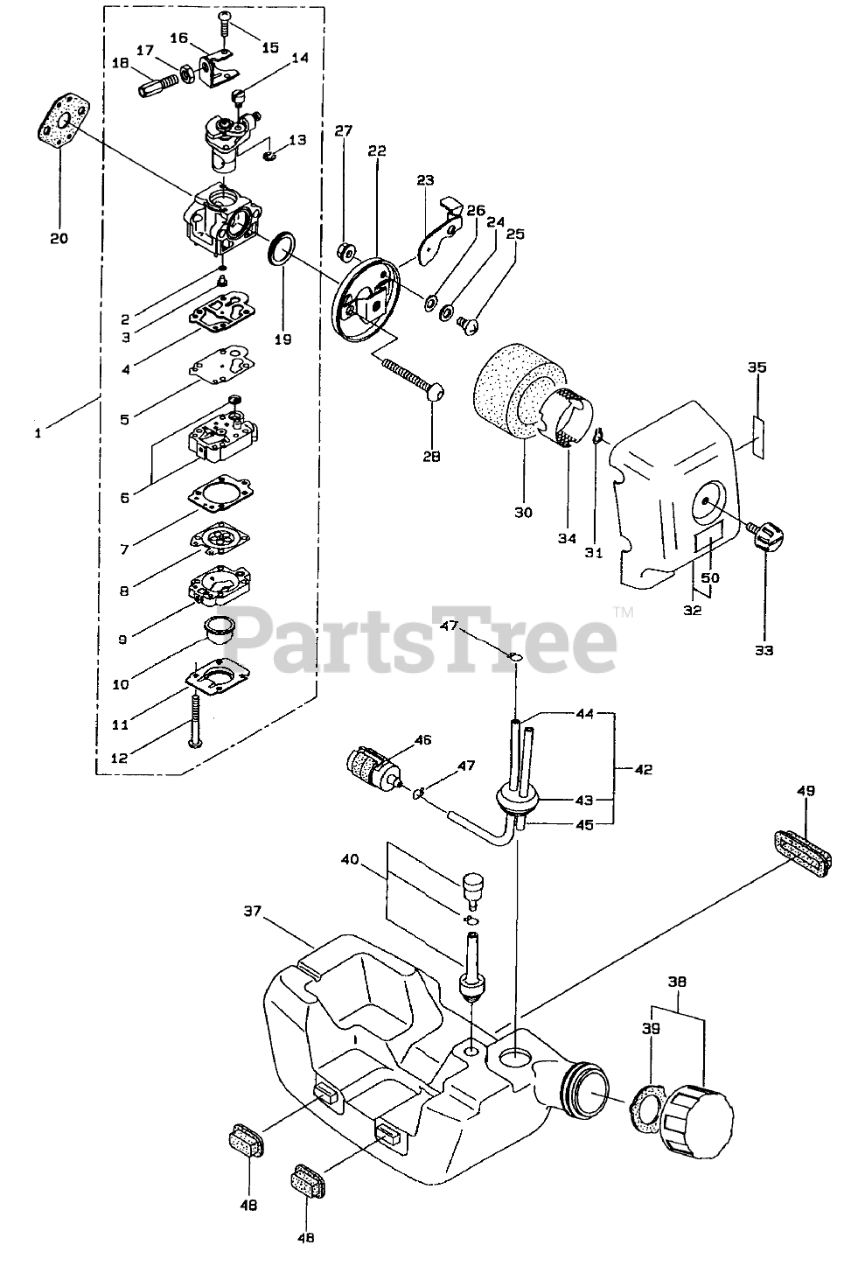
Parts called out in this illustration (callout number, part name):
1	Carburetor Assembly (Incl. Ref. # 2-19)
2	O-RING
3	JET - MAIN #40.5
4	GASKET (NC)
5	PUMP - DIAPHRAGM (NC)
6	PUMP - BODY
7	GASKET (NC)
8	ASM - DIAPHRAGM
9	PURGE - BODY (NC)
10	PRIMER
11	PLATE - COVER (NC)
12	SCREW (NC)
13	E-RING
14	SWIVEL
15	Screw
16	BRACKET
18	ADJUSTER
19	PACKING
20	GASKET
22	BRACKET
23	VALVE - CHOKE
24	PACKING
26	WASHER
30	ELEMENT
32	COVER - AIR FILTER
34	SCREEN
35	LABEL
37	TANK - FUEL
38	Fuel Tank Cap Assembly (Incl. Ref. # 39)
39	PACKING
40	ASM - BREATHER
42	Fuel Pipe Assembly (Incl. Ref. # 42-45)
43	GROMMET
44	PIPE - FUEL
45	PIPE - RETURN
46	ASM - FUEL FILTER
50	DECAL - WARNING
